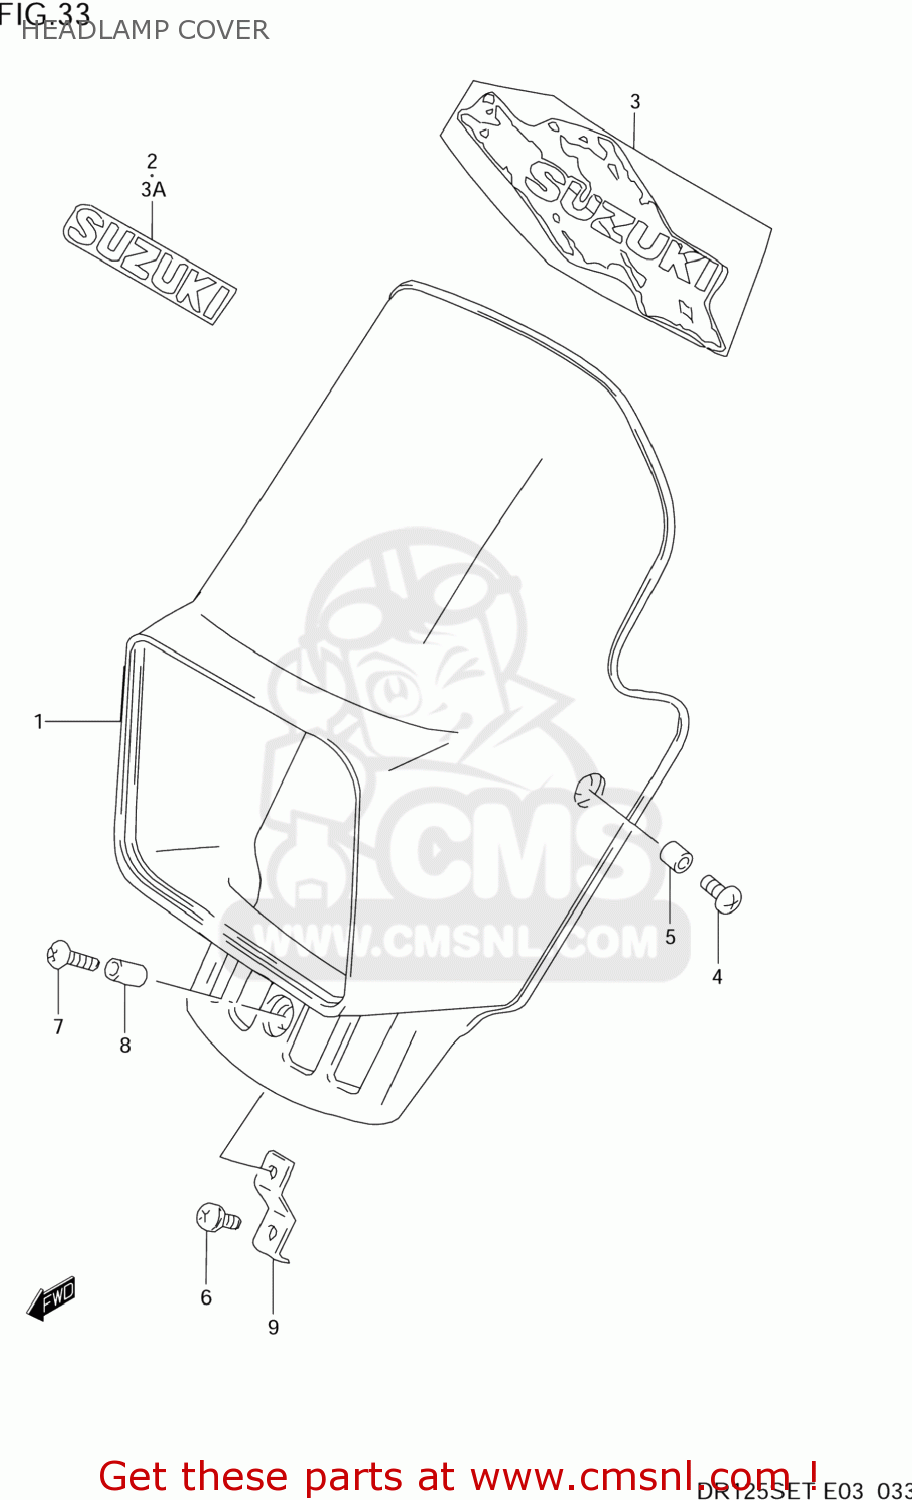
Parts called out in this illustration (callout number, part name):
1	COVER,HEADLAMP
2	EMBLEM,HEADLAMP COVER
3	TAPE,HEADLAMP COVER
3A	EMBLEM,HEADLAMP COVER
4	SCREW 6X12
5	SPACER (6.1X8X3.5)
6	SCREW
7	SCREW
8	SPACER (6.1X8X12)
9	BRACE,HEADLAMP HOUSING LWR
